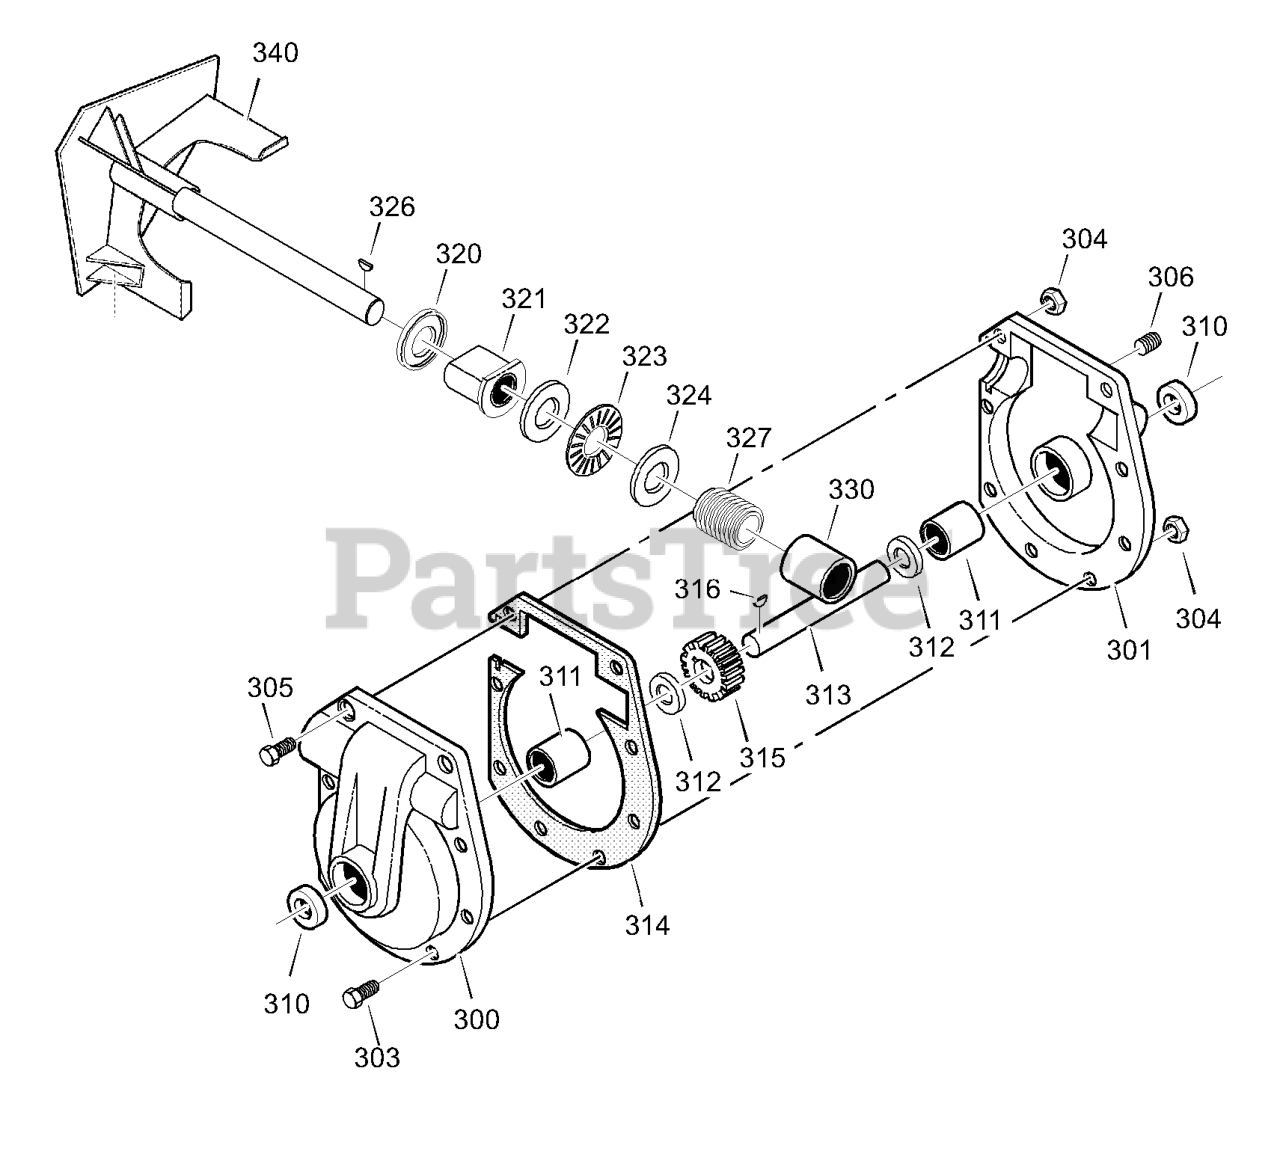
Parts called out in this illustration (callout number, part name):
300	CASE, GEAR, RH
301	CASE, GEAR, LH
303	SCREW,1/4-20X.75
304	NUT,1/4-20
305	NUT, 1/4-20 HEXKEPS
306	SCREW, 3/8-16 x 0.50
310	SEAL, OIL
311	BEARING, FL
312	WASHER, FLAT
313	SHAFT, AUGER OUTPUT
314	GASKET, GEAR BOX
315	WORM GEAR
316	KEY, WOODRUFF #61
320	BRNG, FL
321	SHAFT, AUGER INPUT
322	COLLAR, THRUST
323	PIN, SPRING
324	WASHER, FLAT
326	BRNG, FL
327	SEAL, OIL
330	BEARING
340	IMPELLER
